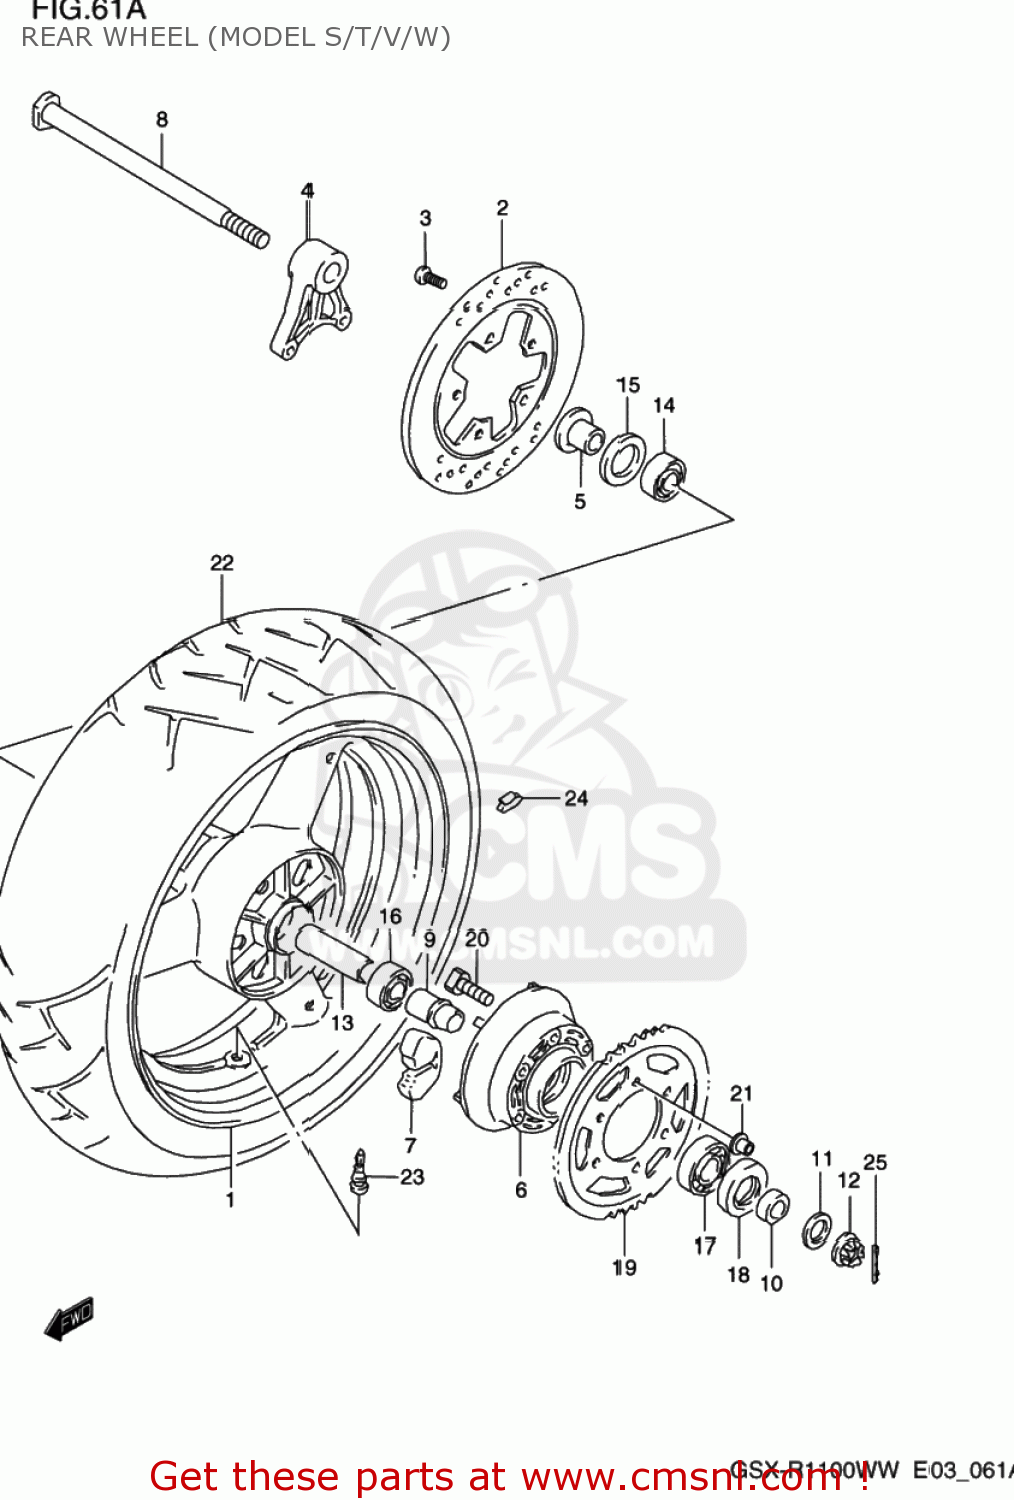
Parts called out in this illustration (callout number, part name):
1	WHEEL,REAR (MT5.50X17)(G
2	DISC,RR BRAKE
3	BOLT 8X33
4	BRACKET,RR CALIPER
5	SPACER,RR AXLE,R
6	DRUM,RR SPROCKET
7	ABSORBER,RR HUB SHOCK
8	AXLE,RR
9	RETAINER,RR HUB BEARING
10	SPACER,RR AXLE,L
11	WASHER(18.5X28X2.6)
12	NUT
13	SPACER,RR WHEEL HUB BEARING
14	BEARING(20X47X14)
15	SEAL,OIL(28X47X7)
16	BEARING(20X47X14)
17	BEARING(25X62X17)
18	SEAL,OIL(35X62X8)
19	SPROCKET,RR(NT:44-532)
20	BOLT
21	NUT
22	TIRE,REAR 180/55 ZR17
23	VALVE ASSEMBLY,WHEEL,TR412
24	BALANCER,WHEEL (10G)
25	PIN, COTTER
